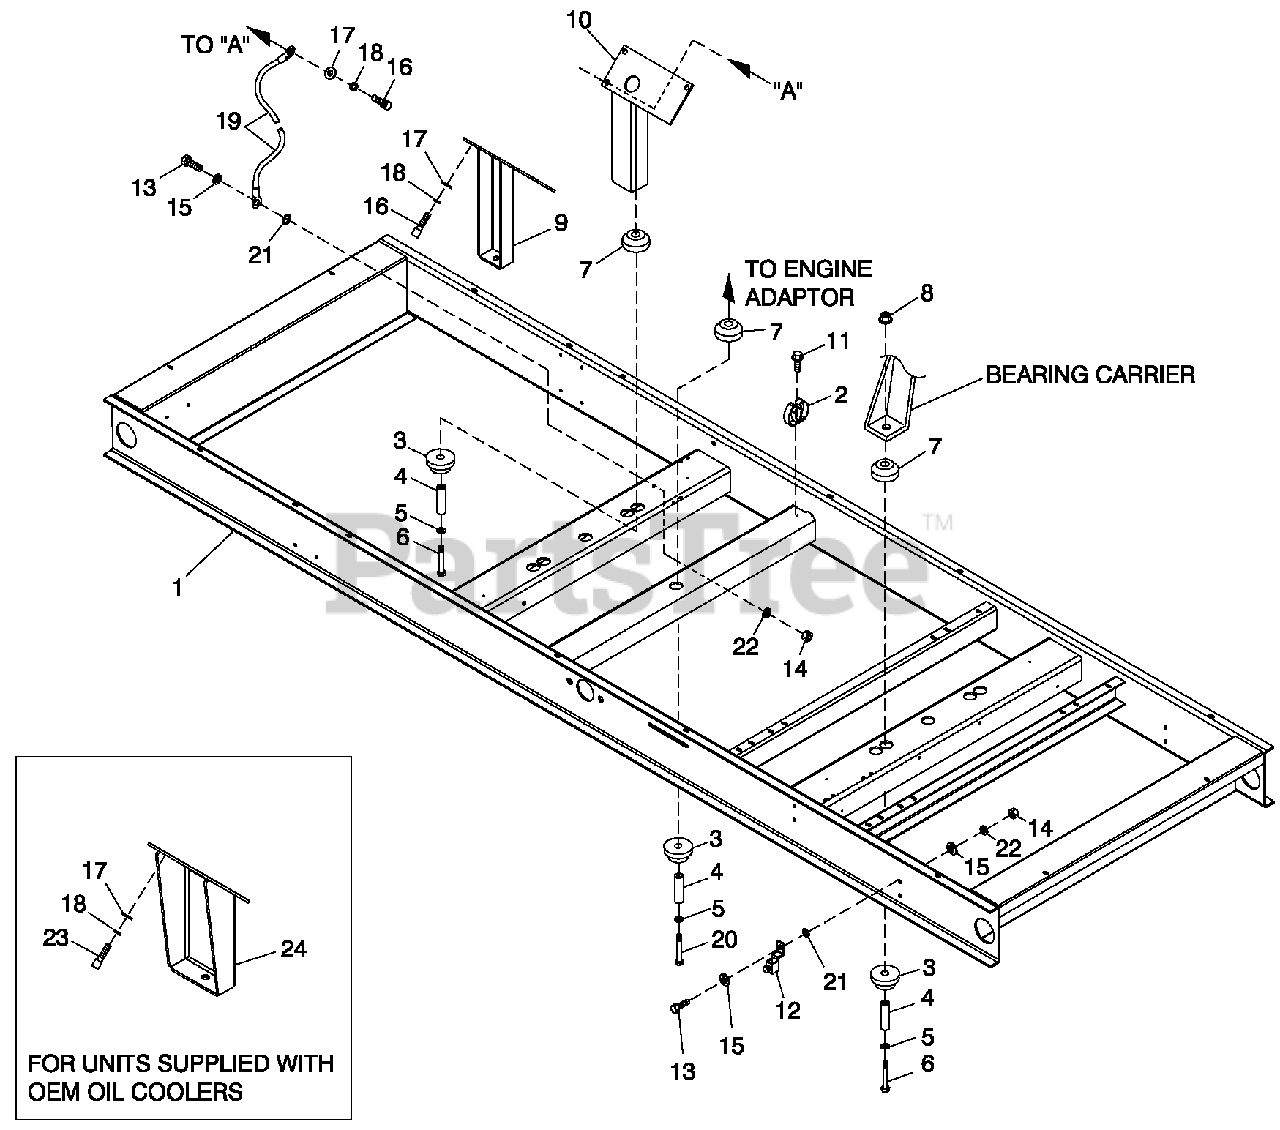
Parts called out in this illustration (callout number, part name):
1	MTG BASE C5 4.6/80KW 5.4/100KW
2	SPRING CLIP HOLDER .37-.62
3	DAMPENER VIBRATION
4	SPACER .49 X .62 X 1.87 PWDR/ZINC
5	WASHER FLAT M12
6	SCREW HHC M12-1.75 X 85 G8.8
7	DAMPENER VIBRATION 50 WHITE
8	NUT LOCKING M12-1.75
9	SUPPORT ENG 4.6L LH
10	SUPPORT ENG 4.6L RH
11	SCREW HHTT M4-0.7X8BP
12	LUG SOLDERLESS 3/0-#4 X 13/32 CU
13	SCREW HHC M6-1.0X 25 G8.8
14	NUT HEXM6X1.0G8YEL CHR
15	WASHER FLAT 1/4-M6 ZINC
16	SCREW SHC M10-1.5 X 30 G12.9
17	WASHER FLAT 3/8-M10 ZINC
18	WASHER LOCK M10
19	ASSY WIRE 14.00"
20	SCREW HHC M12-1.75 X 80 G10.9
21	WASHER SHAKEPROOF EXT 5/16 STL
22	WASHER LOCK M6-1/4
23	SCREW SHC M10-1.5 X 60 C12.9
24	SUPPORT ENGINE LH
